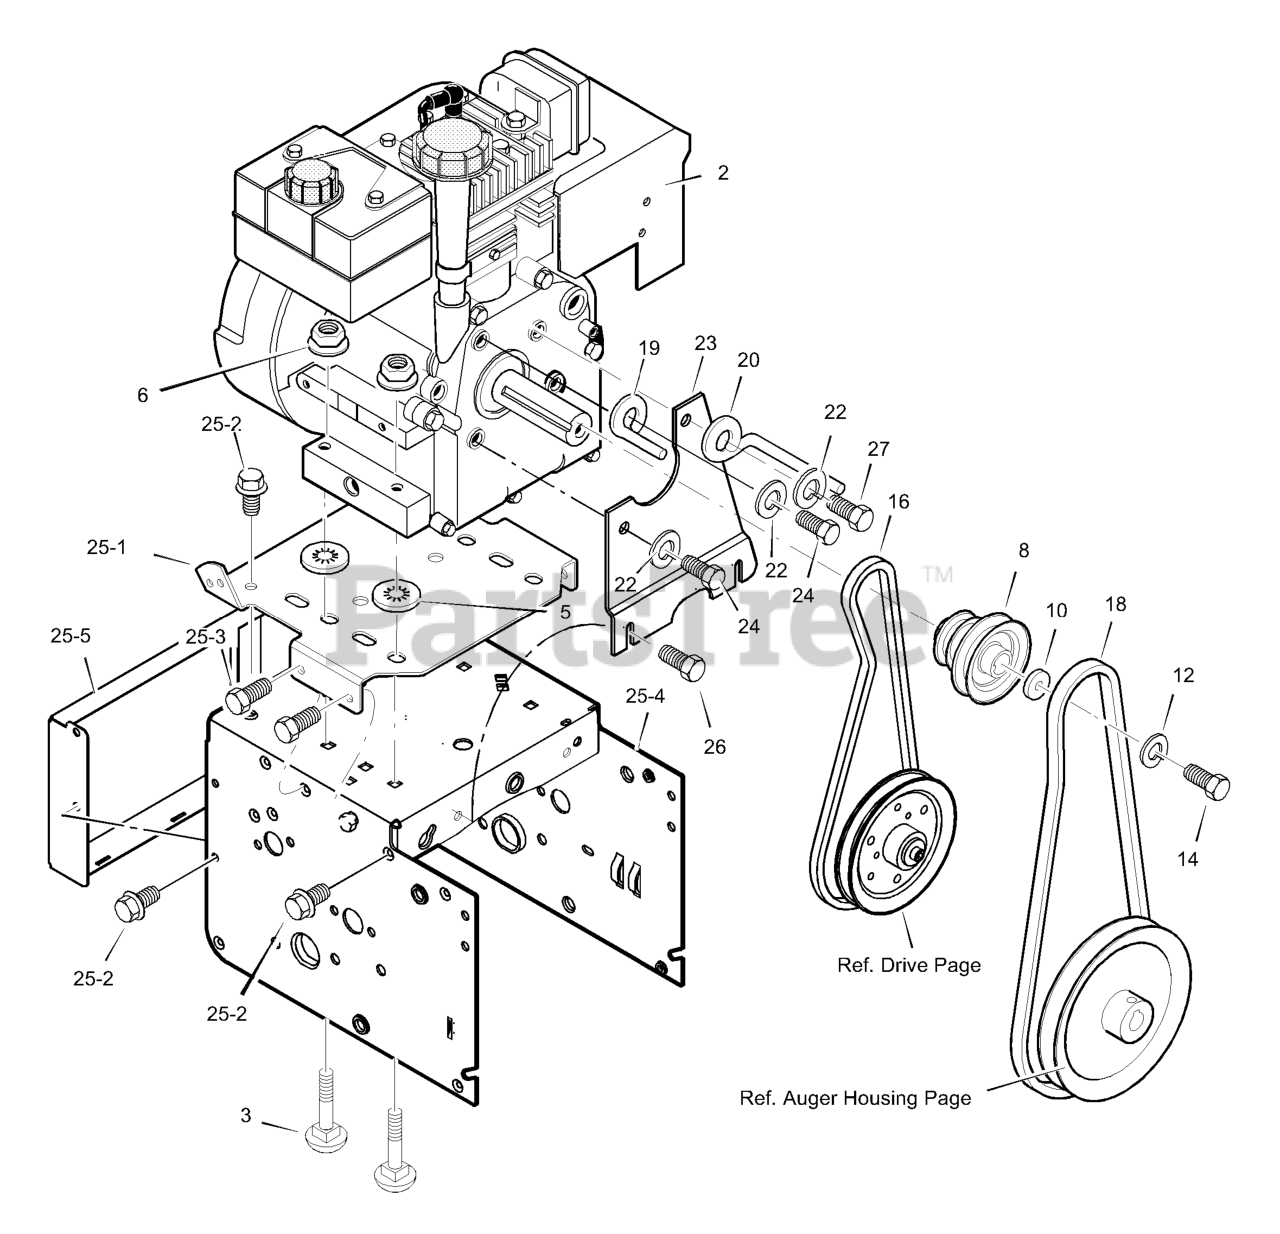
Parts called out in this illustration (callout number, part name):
2	ENGINE
3	BOLT, CARRIAGE 5/16-18
5	RETAINER, PUSH
6	NUT, HEX 5/16-18
8	PULLEY, ENGINE
10	WASHER
12	WASHER
14	SCREW, 3/8-24 x 1.00
16	BELT, HYDRO DRIVE
18	BELT, AUGER V 4L
19	GUIDE, BELT
20	GUIDE, BELT
22	WASHER, .31X.58X.08
23	PLATE, VIBRATION
24	SCREW, 5/16-24 x 0.75
25	FRAME ASSEMBLY
25-1	PLATE, ENGINE MOUNT
25-2	SCREW, TAP 1/4-20 X .63
25-3	SCREW, TAP 5/16-18 X .50
25-4	FRAME, MOTOR BOX
25-5	PANEL, BACK - HYDRO
27	BOLT, HEX 5/16-24 X 1.00
